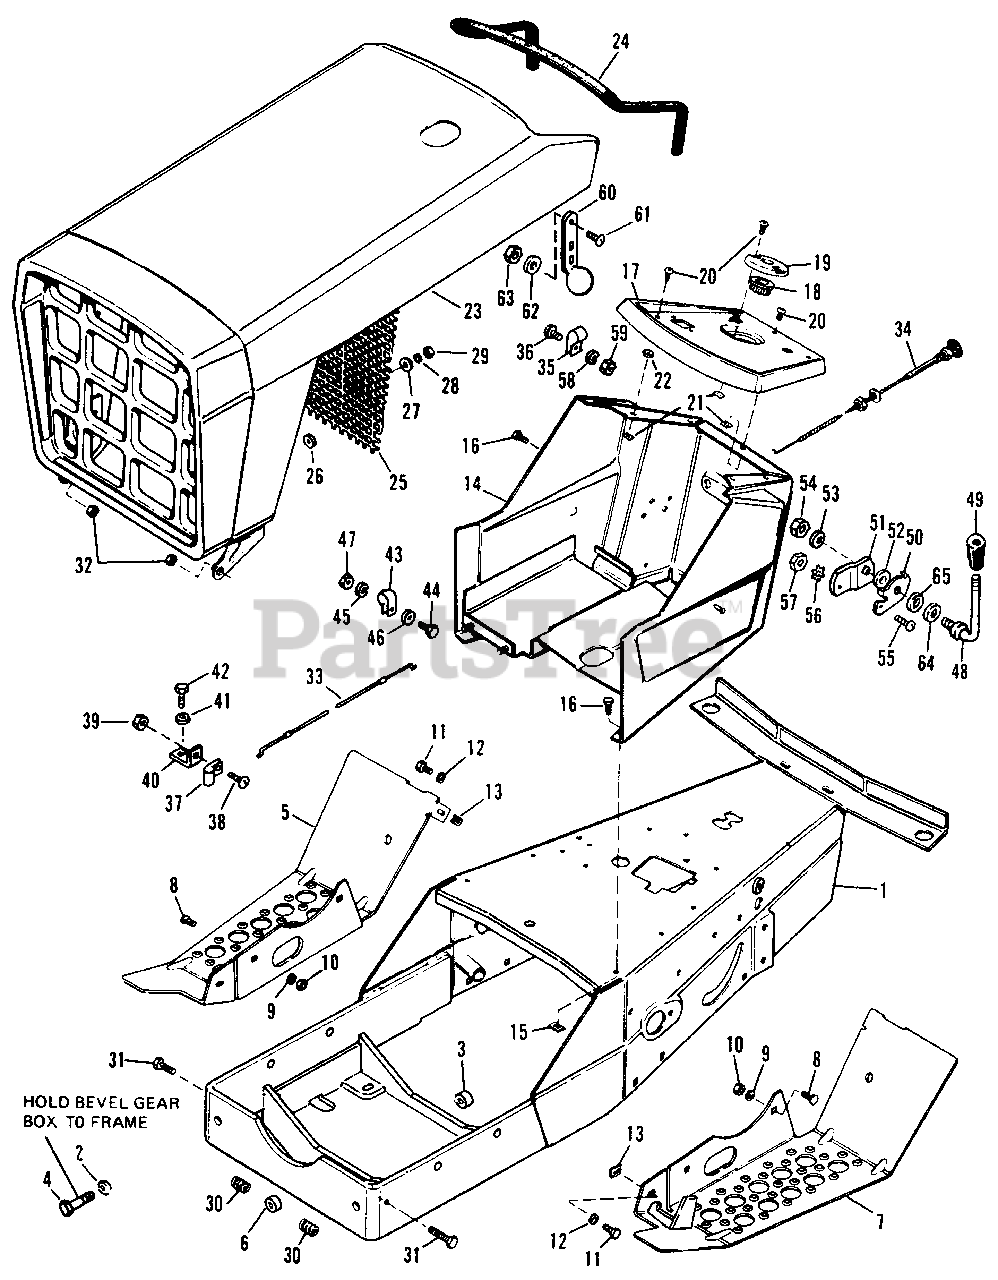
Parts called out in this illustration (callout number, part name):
1	Frame Assembly
2	Lockwasher, 7/16"'
4	Hex Capscrew, 7/16"-14 N.C. x 1-1/2"
5	Foot Rest, R.H.
7	Foot Rest, L.H.
8	Carriage Bolt, 5/16"-18 N.C. x 3/4"
9	Lockwasher, 5/16"
10	Full Hex Nut, 5/16"-18 N.C.
11	Hex Capscrew, 5/16"-18 N.C. x 3/4"
12	Lockwasher, 5/16"
13	Nut, Tinnerman, 5/16"-18 N.C.
14	Dash Assembly
15	Nut, Tinnerman
16	Hex Head Self Tapping Screw, No. 14 AB x 3/4"
17	Panel, Instrument
18	Bushing, Steering
19	Plate, Steering Adj.
20	Round Head Phillips Screw, 1/4"-20 N.C. x 1/2"
21	Nut,Tinnerrnan, 1/4"-20 N.C.
22	Plain Washer
23	Grille & Hood Assembly
24	Molding, Hood
25	Screen, Grille
28	Lockwasher, Shakeproof No.10
29	Full Hex Nut, No. 10-24 N.F.
31	Hex Capscrew, 3/8"-16 N.C. x 1-1/2"
32	Hex Lock Nut, Center, 3/8"-16 N.C.
33	Throttle Control
34	Choke Control
35	Clip, Bowden Wire
36	Self Tapping Rd. Hd. Screw, No. 10-24 N.C. x 1/2"
37	Clip, Bowden Wire
38	Rd. Hd. Machine Screw, No. 10-32 N.F. x 3/8"
39	Full Hex Nut, No. 10-32 N.F.
40	Bracket, Throttle Cable
41	Lockwasher, 1/4"
42	Self Tapping Rec. Hex Hd. Screw, 1/4"-20 N.C. x 5/8"
44	Hex Capscrew, 1/4"-20 N.C. x 5/8"
45	Lockwasher, 1/4"
46	Plain Washer, 1/4" Std.
47	Full Hex Nut, 1/4"-20 N.C.
48	Throttle Handle
49	Knob
50	Stop Throttle
51	Arm Throttle
53	Washer Lock Dished Type, 3/8"
54	Full Hex Lock Nut, 3/8"-16 N.C.
55	Round Hd. Machine Screw, No. 10-32 x 1/2"
56	Lockwasher, No. 10 Shakeproof
57	Full Hex Nut, No. 10-32
58	Lockwasher, No. 12
59	Full Hex Nut, No. 10-24
61	Phillips Head Truss Screw, No. 10-32 x 1/2"
63	Lock Nut, No. 10-32
